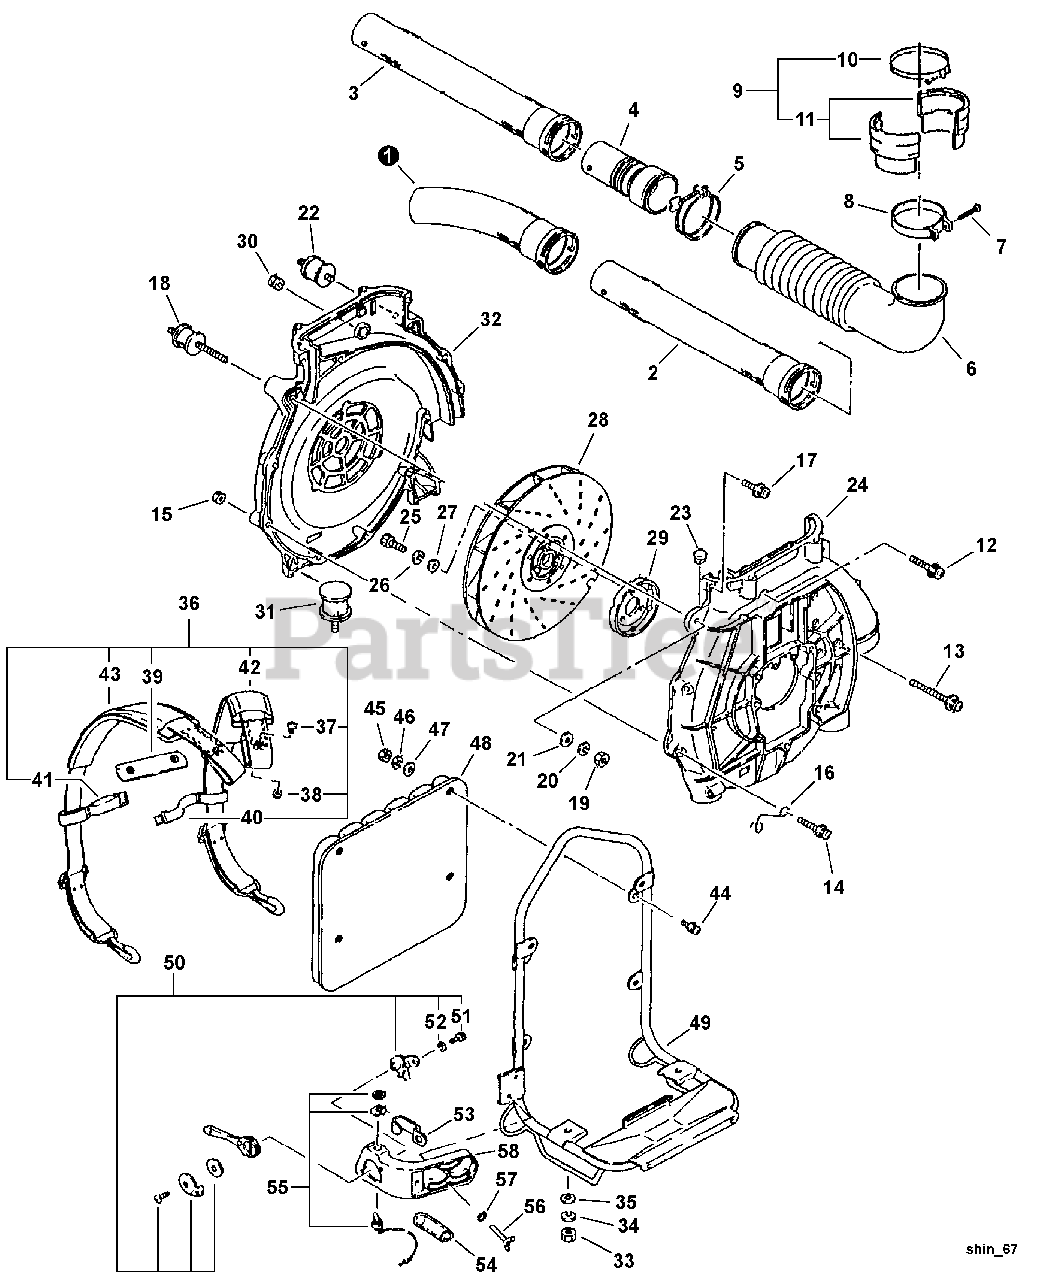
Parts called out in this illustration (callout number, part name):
1	TUBE, BLOWER - CURVED
2	TUBE, BLOWER - STRAIGHT
3	TUBE, BLOWER - STRAIGHT
4	JOINT, BLOWER TUBE
5	CLAMP - B
6	TUBE, BLOWER - FLEXIBLE
7	CLAMP KIT
8	CLAMP KIT
9	JOINT ASSY
11	SWIVEL JOINT KIT
12	SCREW - 5X45
13	SCREW - 5X80
14	SCREW - 5X45
15	NUT - 5
16	CLIP, CABLE
17	SCREW - 5X30
18	CUSHION
19	NUT - 5
20	LOCKWASHER - 5
21	WASHER
23	GROMMET
24	COVER, FAN - OUTER
25	SCREW - 6X25
26	LOCKWASHER - 6
27	WASHER - 6
28	FAN
29	DEFLECTOR, AIR
30	GROMMET A
32	COVER, FAN - INNER
33	NUT - 6
34	LOCKWASHER - 6
35	WASHER
36	HARNESS ASSY
37	SCREW - 6X16
38	LOCKNUT - 6
39	CONNECTOR, STRAP
40	BAND - RIGHT
41	BAND - LEFT
42	STRAP
43	STRAP
44	SCREW - 5X10
45	NUT - 5
46	LOCKWASHER - 5
47	WASHER
48	PAD
49	FRAME, BACKPACK
50	THROTTLE LEVER ASSY
51	SCREW - 6X10
52	LOCKWASHER - 6
53	CLAMP, WIRE
54	TUBE
55	SWITCH, IGNITION
56	THUMBSCREW
57	WASHER - TOOTH
58	BRACKET
